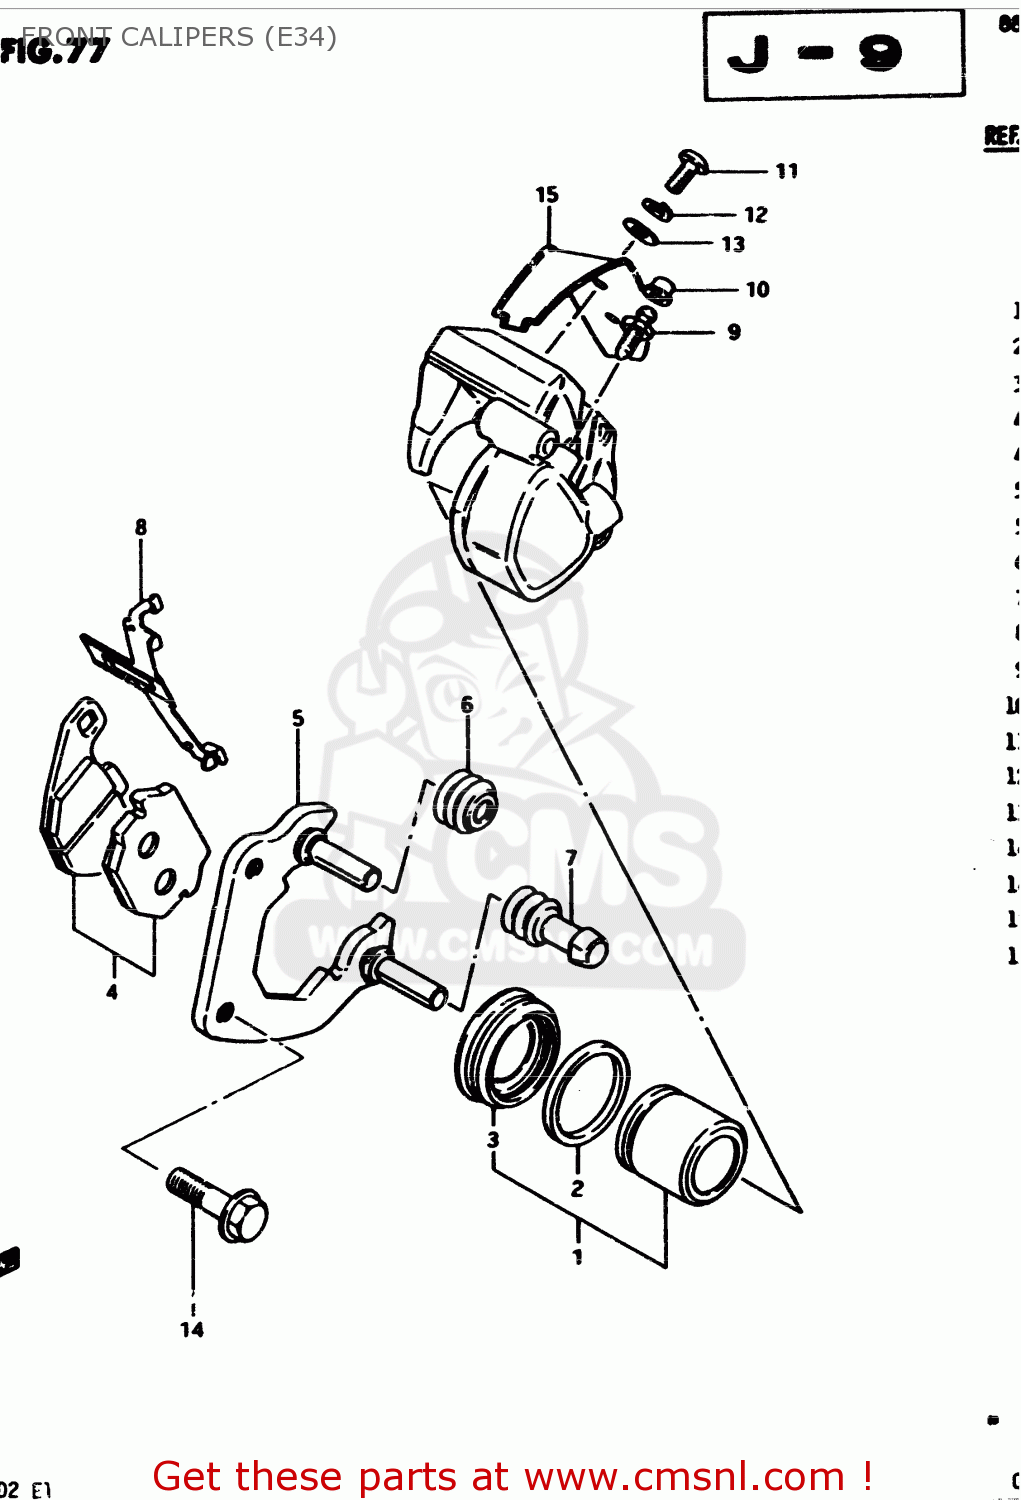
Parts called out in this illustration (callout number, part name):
1	PISTON SET
2	SEAL,PISTON
3	BOOT,PISTON
4	PAD SET,BRAKE (MCA)
5	CARRIER,CALIPE
6	BOOT,AXLE
7	INSULATOR,AXLE
8	SPRING,PAD
9	BLEEDER
10	CAP,BREATHER
11	SCREW
12	LOCK WASHER
13	WASHER
14	BOLT
15	COVER
